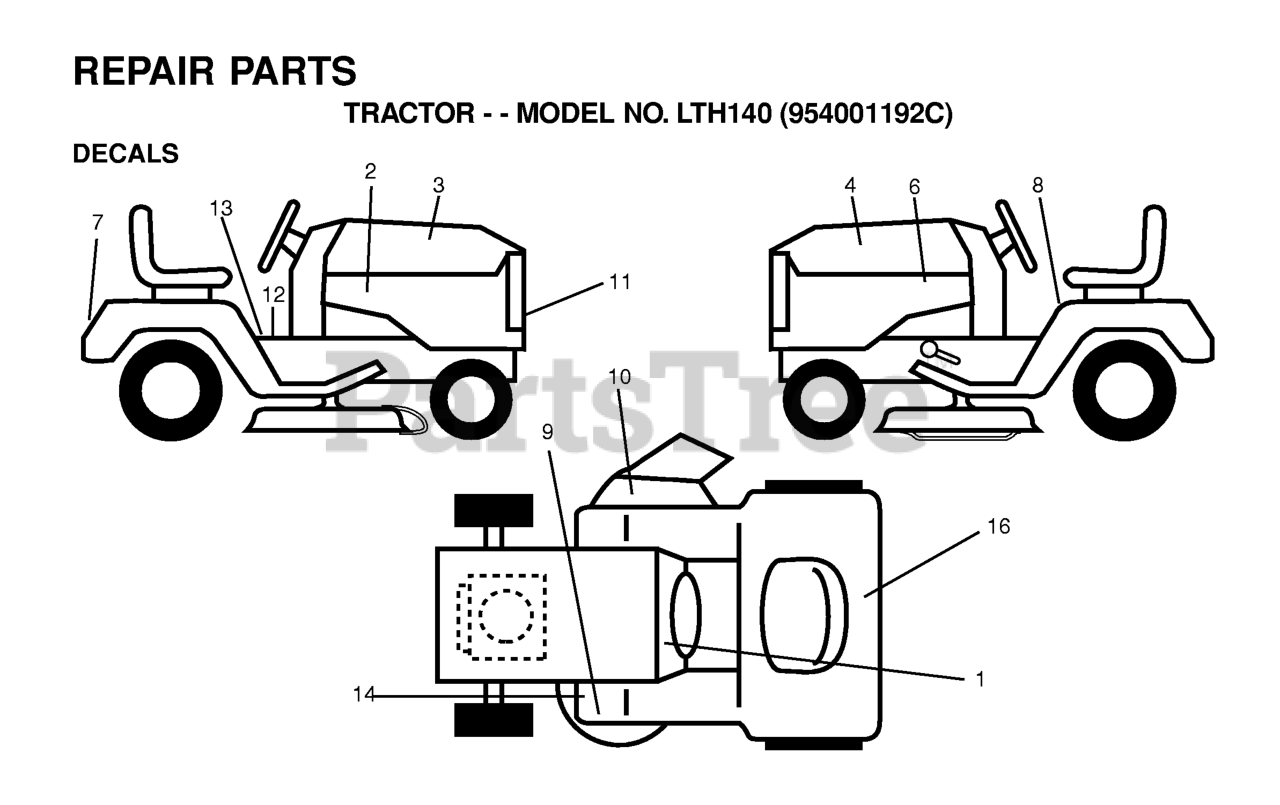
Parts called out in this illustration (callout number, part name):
3	DECAL-HOOD R.H.
4	DECAL-HOOD L.H.
7	DECAL FENDER NLA
8	DECAL CAUTION
10	DECAL WARNING (ENGLISH/FRENCH)
11	DECAL GRILL HUSQ NLA
13	DECAL PARK BRAKE
14	DECAL V-BELT SCHEMATIC
16	DECAL BTRY SYMBOLS
